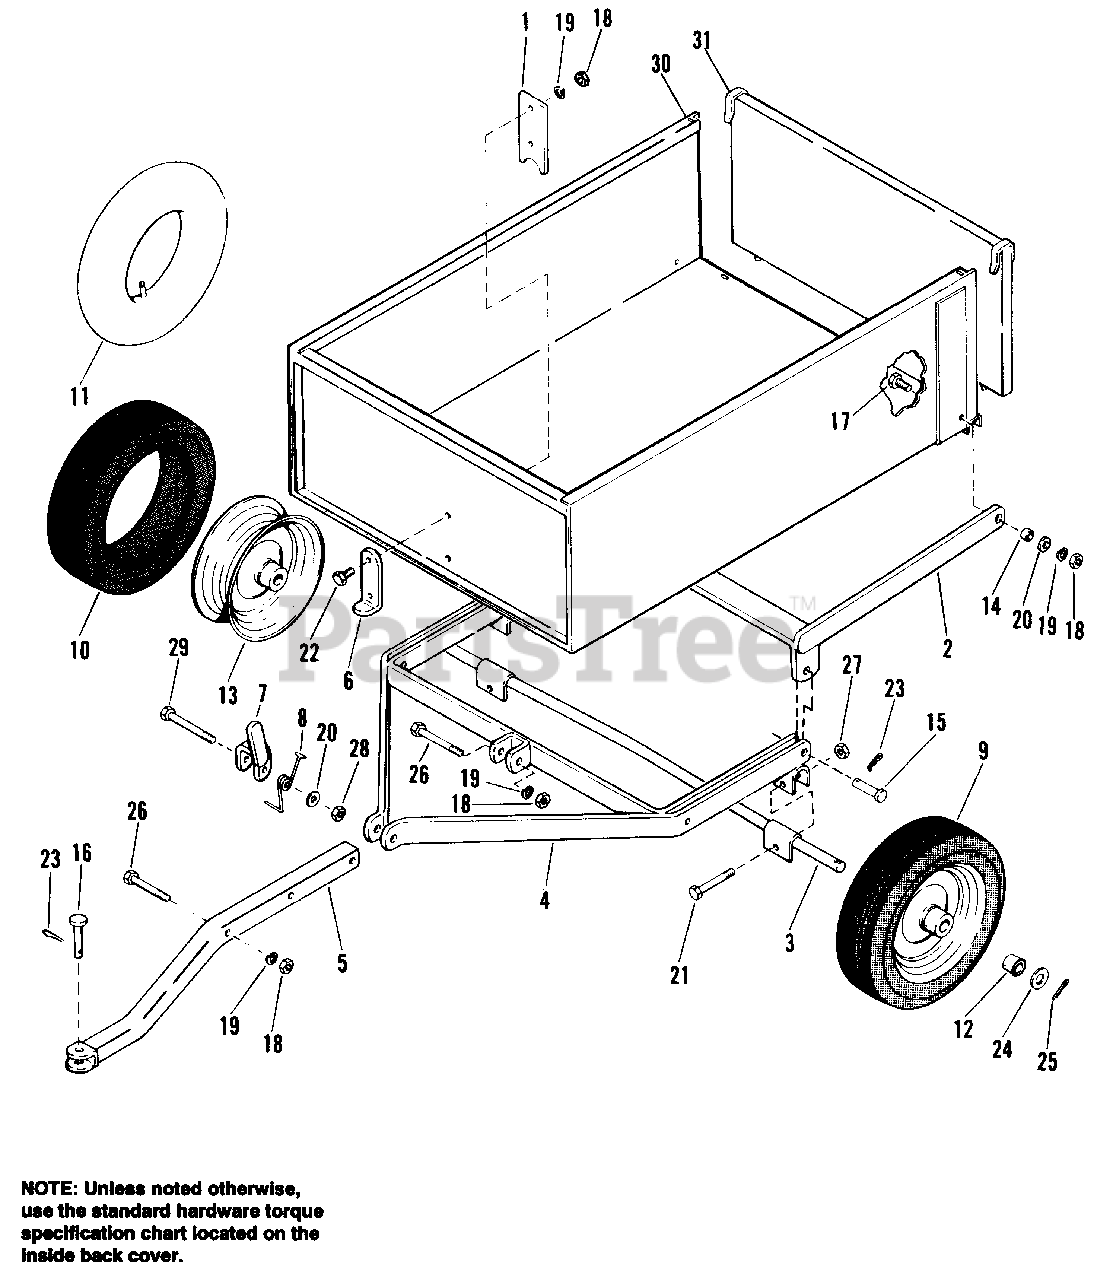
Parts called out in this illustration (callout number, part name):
1	PLATE, Box Guide
2	PIVOT ASSY., Box
3	AXLE ASSY.
4	FRAME ASSY.
5	TONGUE ASSY.
6	PLATE, Box Catch
7	CLEVIS ASSY.
8	SPRING, Torsion
9	WHEEL & TIRE ASSY., Dico Tires (Incl. Ref. Nos. 10, 11, 12, 13)
9	WHEEL & TIRE ASSY., Carlisle Tires (Incl. Ref. Nos. 10, 11, 12, 13)
10	TIRE, Carlisle
11	TUBE, 4.00 x 8
12	BEARING
17	CAPSCREW, Hex, 3/8-16 x 1
18	NUT, Hex, Full, 3/8-16
19	LOCKWASHER, 3/8
20	WASHER, 3/8
21	CAPSCREW, Hex Head 5/16-18 x 2 G5
22	CAPSCREW, Hex, 3/8-16 x 1-1/4
23	PIN, Quick
24	WASHER, Plain, 3/4
25	PIN, Cotter, 3/16 x 1-1/2
26	CAPSCREW, Hex, 3/8-16 x 2-1/4
27	NUT, Hex, Full, 5/16-18
28	NUT, Hex, Centerlock, 3/8-16
29	CAPSCREW, Hex, 3/8-16 x 2-3/4
30	TRAILER & END GATE ASSY.
